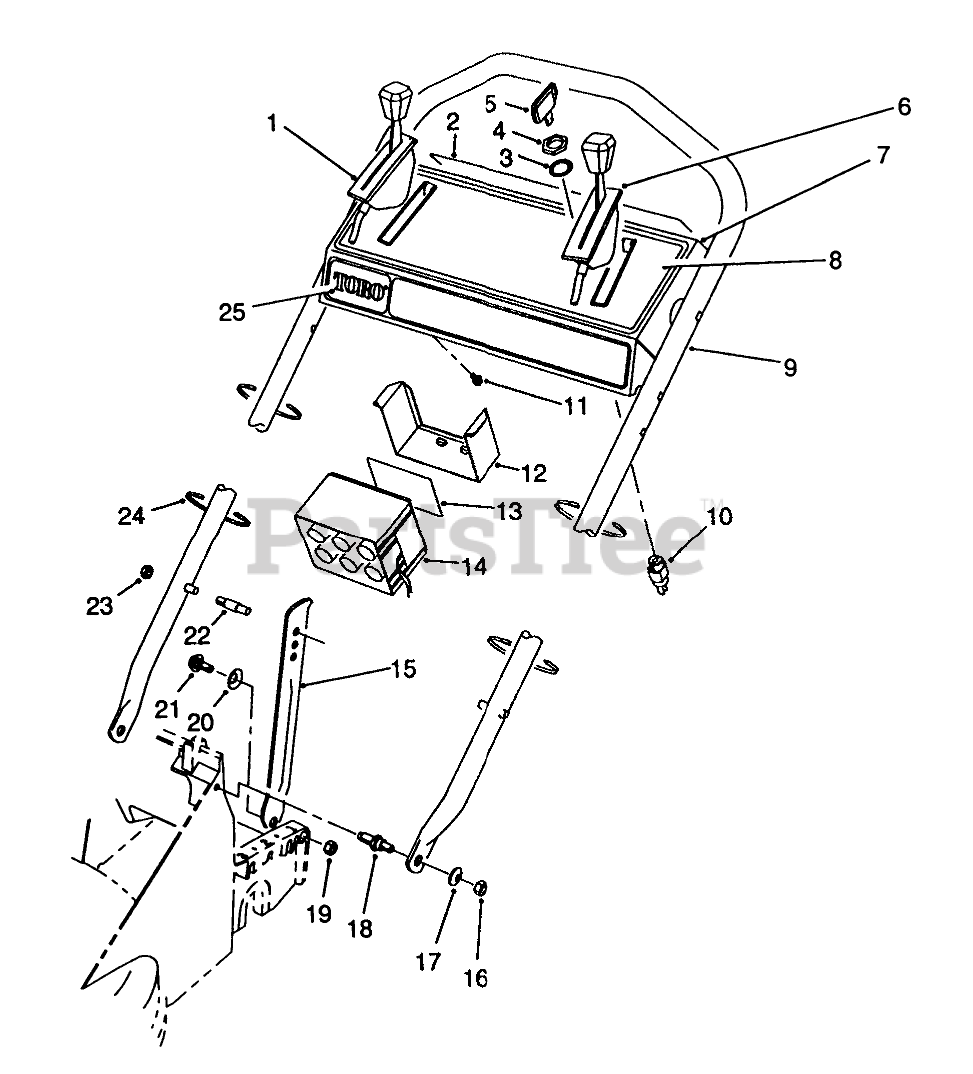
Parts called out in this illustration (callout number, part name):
1	Control-Ground Speed Bend Type #3 Sheath Lg. 51-1/4" Wire Lg. 2-1/8"
2	DECAL - PANEL, REAR
3	KEY-IGNITION
4	NUT-HH
5	WASHER-TOOTH, INTERNAL
6	ControI-Throttle Bend Type #2 Sheath Lg. 44-3/4" Wire Lg. 2-1/2"
7	Panel-Control (Incl. Ref. #8)
8	DECAL - INSTRUCTION
9	HANDLE
10	Switch-Starter (Incl. Ref. #4 & 5)
11	SCREW-HWHTF
12	Retainer-Battery
13	Decal
14	Battery (Incl. Ref. #13)
15	HANDLE LATCH
16	NUT-LOCK
17	WASHER-PLAIN
18	CLAMP
19	NUT-LOCK, NI
20	WASHER-BELLEVILLE
21	SHOULDER SCREW LATCH
22	HANDLE PIN
23	NUT-LOCK, NI
24	TIE-CABLE
25	DECAL - KEY LECTRIC
